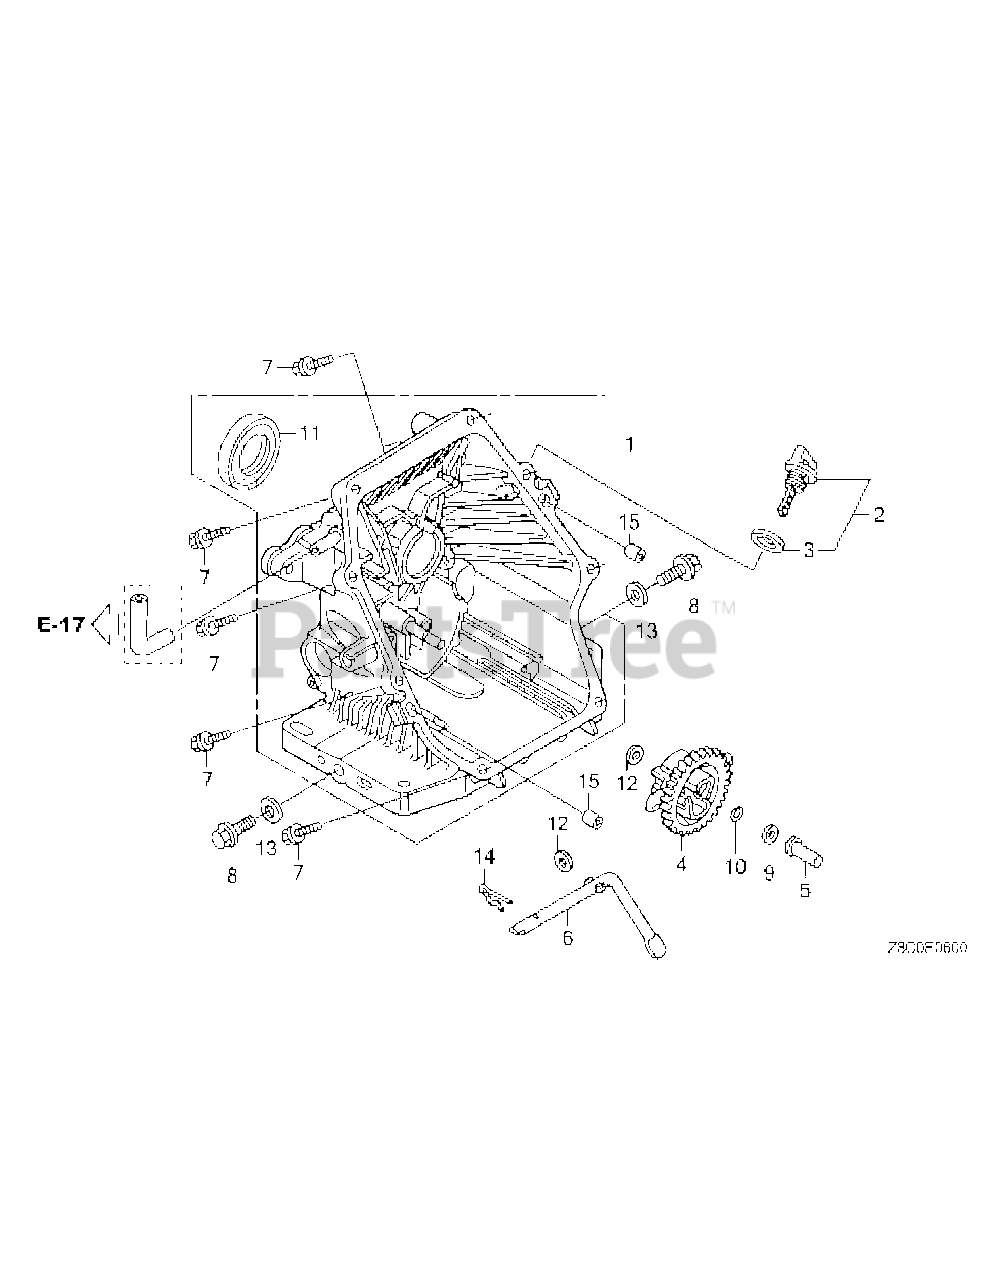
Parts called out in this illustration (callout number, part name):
1	Cover Assy., Crankcase
2	Cap Assy., Oil Filler
3	Packing, Oil Filler Cap
4	Governor Assy.
5	Slider, Governor
6	Shaft, Governor Arm
7	Bolt, Flange, 6X25 (Ct200)
8	Bolt, Drain Plug, 12X15
9	Washer, Thrust, 6Mm
10	Clip, Governor Holder
11	Oil Seal, 28X41.25X6
12	Washer, Plain, 6Mm
13	Washer, Drain Plug, 12Mm
14	Pin, Lock, 8Mm
15	Dowel Pin, 8X20
